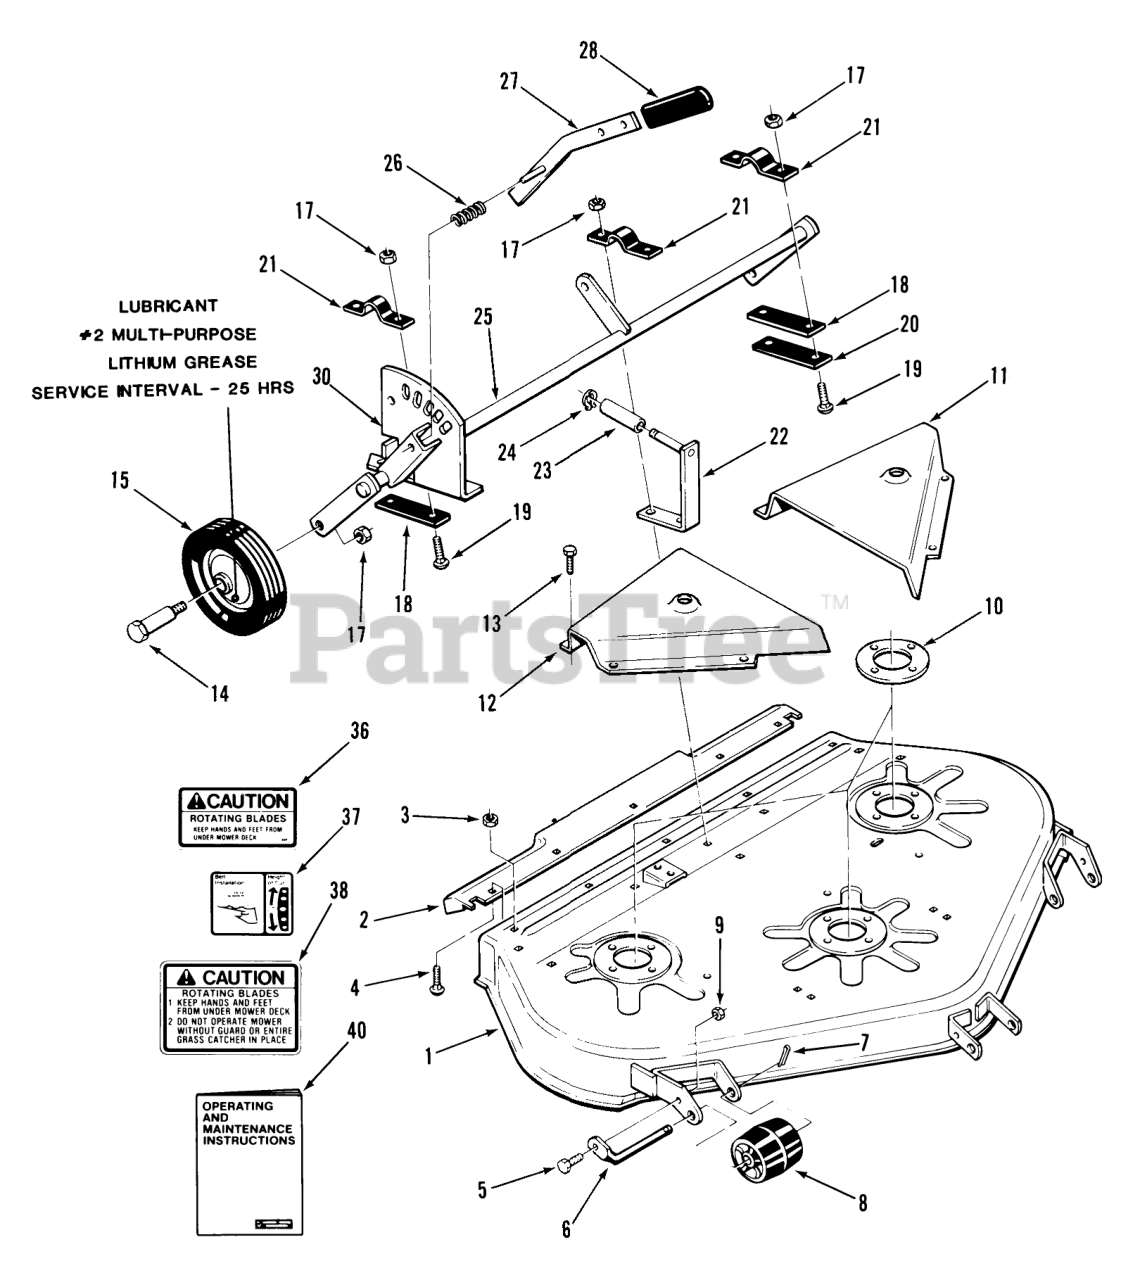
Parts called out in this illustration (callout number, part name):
1	Mower Deck
2	EXTENSION R
3	Nut
4	Bolt
5	H H C S
6	ROLLER-SHAFT
7	Cotter Pin
8	Roller
9	Nut
10	PLATE-SPINDLE
11	Belt Cover LH
12	Belt Cover RH
13	Bolt
14	BOLT-SHOULDER
15	WHEEL
17	Nut
18	STRAP 1/16 B
19	Bolt
20	Bar
22	Bracket Guide
23	SPACER
24	Snap Ring
25	Gage Wheel Support
26	SPRING-COMPRESSION
27	Lever
30	Quadrant
36	Caution Decal
37	DECAL-HEIGHT BELT
38	Decal-Caution
40	Operating & Maintenance Instructions
